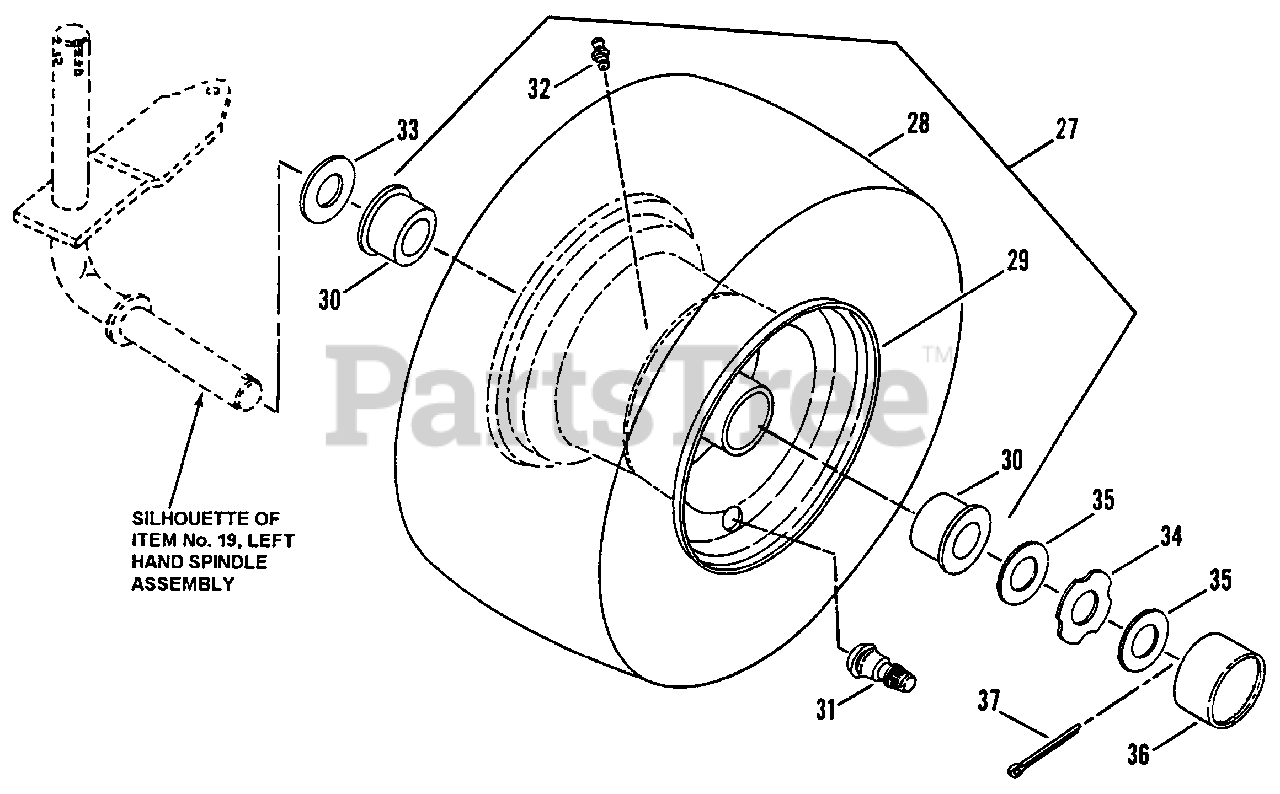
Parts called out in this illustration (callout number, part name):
27	ASSEMBLY, Front Tire & Rim
28	TIRE, 13 x 5.00
29	RIM, 5.50 x 4.00
30	BEARING, Wheel
31	VALVE, Air (Snap-In)
32	FITTING, Lube 1/4-28 Tapered Thread
33	WASHER, Flat, .15 x .78 I.D. x 1.5" O.D.
34	WASHER, Hub-Cap Retaining
35	WASHER, Flat,.07x.77 I.D. x 1.31" O.D.
36	HUB-CAP
37	COTTER-PIN, 5/32 x 1"
